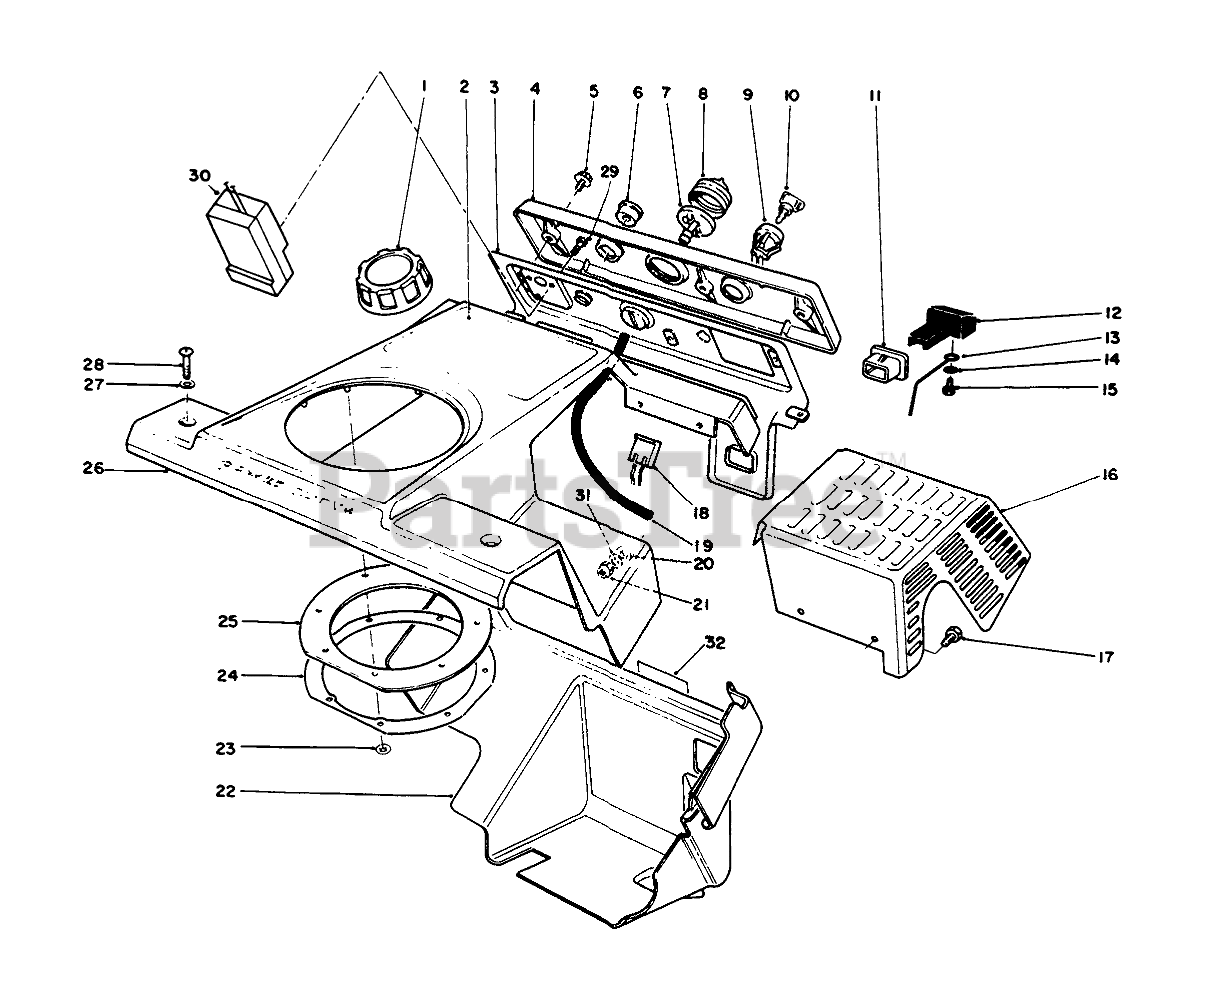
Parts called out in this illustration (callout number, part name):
1	CAP-FUEL ASM
2	DECAL - CCR 2000E
3	Panel-Control (Incl. Ref. #6-8 & 11)
4	Plate-Name
5	SCREW-HWHTF
6	GUIDE-ROPE, STARTER
7	BODY-PRIMER
8	BULB-PRIMER
9	SWITCH
10	KEY-IGNITION
11	FITTING
12	CONTROL-CHOKE
13	Unkage-Choke
14	WASHER-PLAIN
15	SCREW-PPH
16	Wa-Shield
17	SCREW-SHH
18	CONNECTOR-BODY
19	PRIMER HOSE
20	WASHER
21	NUT-LOCK, NI
22	LOWER SHROUD
23	PALNUT
24	Retainer-Chute Seal
25	SEAL-CHUTE
26	Upper Shroud Assembly (Incl. Ref. #2 & 23-25)
27	WASHER-FLAT
28	SCREW-PPH
29	SCREW-PLASTITE
30	Switch Assembly
31	WASHER-FLAT
32	DECAL
